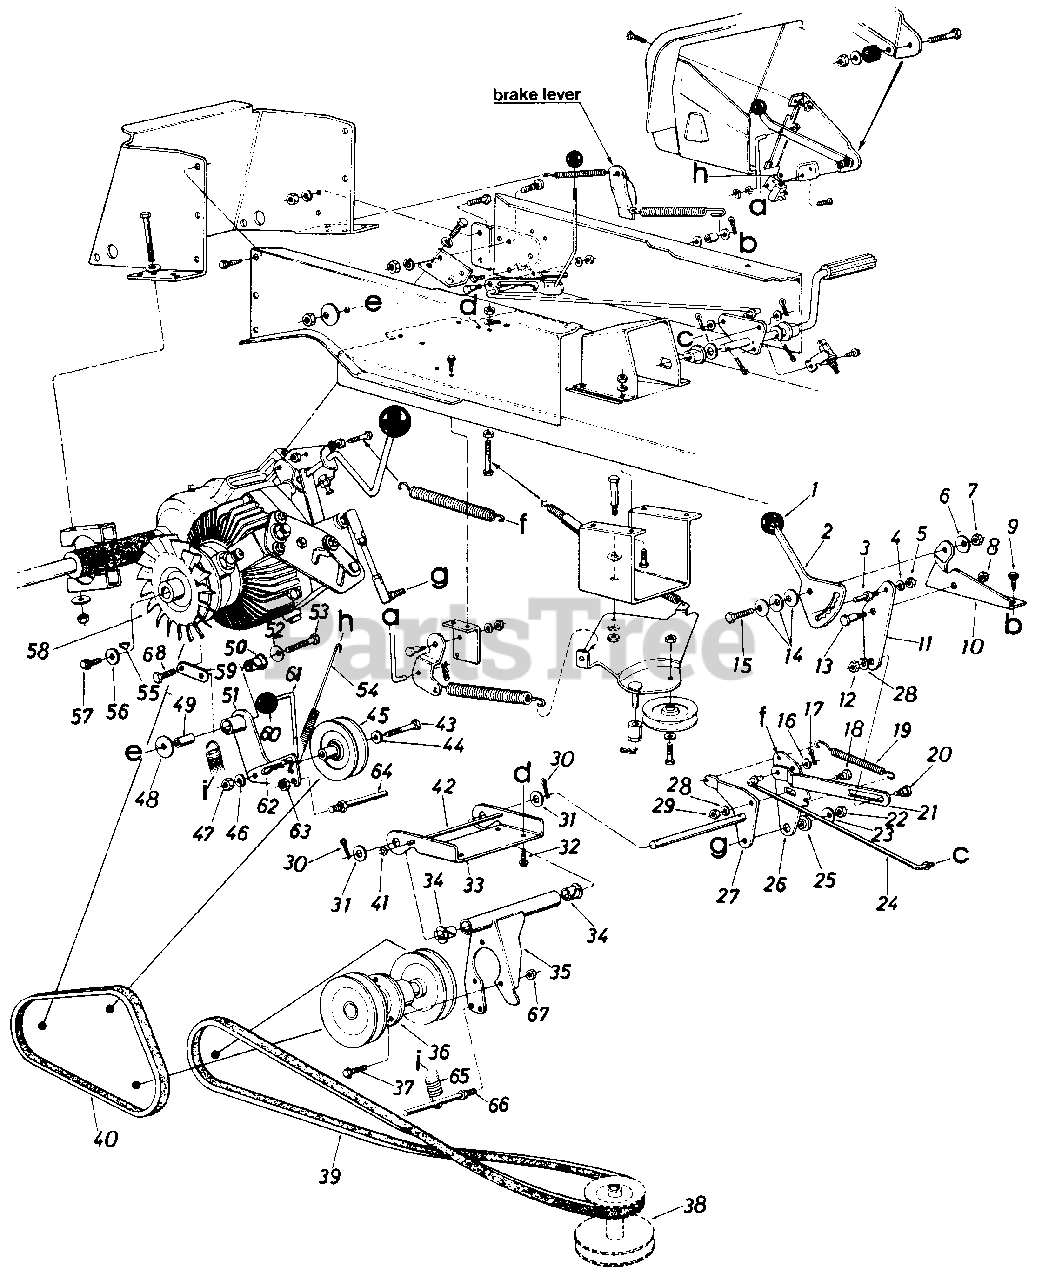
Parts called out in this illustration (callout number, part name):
1	Gear Shift Knob
2	Speed Selector Cam
3	Hex Stud .250" Dia. x .62"
4	L-Wash. 1/4" I.D.
5	Hex Nut 1/4-20 Thd.
6	Bell-Wash. .400" I.D. x 1.13" O.D.
7	Hex Ins. L-Nut 3/8-24 Thd.
8	Hex Top L-Nut 3/8-16 Thd.
9	Hex Wash. Hd. S-Tap Scr. 1/4-20 x .75" Lg.
10	Speed Selector Mtg. Brkt.
11	Speed Selector Transfer Brkt.
12	Hex Nut 5/16-18 Thd.
13	Shld. Bolt .500" Dia. x .170
14	Bell-Wash. .39" I.D. x 1.13" O.D.
15	Hex Bolt 3/8-24 x 1.00" Lg.
16	Fl-Wash. .385" I.D. x .87" O.D.
17	Cotter Pin 3/32" Dia. x .75" Lg.*
18	Shld. Bolt .437" Dia. x .180
19	Extension Spring .50" Dia. x 2.75" Lg.
20	Shld. Bolt .437" Dia. x .180
21	Speed Selector Link
22	Hex Nut 3/8-24 Thd.
23	Bell-Wash .39" I.D. x 1.13" O.D.
24	Rod-Speed Control .312" Dia.
25	Shld. Spacer .625" I.D.
26	Speed Cont. Transfer Swivel Brkt.
27	Speed Control Transfer Ass'y.
28	L-Wash. 5/16" l.D.
29	Hex Nut 5/16-18 Thd.
30	Cotter Pin 1/8" Dia. x 1.00" Lg.*
31	Fl-Wash. .640" I.D. x 1.24" O.D.
32	Hex Wash S-Tap Scr. 1/4-20 x .50" Lg.
33	Idler Mtg. Brkt.
34	Flanged Nyliner Brg. .376 I.D. x .437
35	Mounting Brkt. Ass'y.
36	Jack Shaft Ass'y.
37	Hex Sems Bolt 5/16-18 x .75" Lg.
38	Engine Pulley 47.5" I.D. x 5.56" O.D.
39	"V"-Belt
40	"V"-Belt
41	Push Cap
42	Rod-3/16" Dia. x 7.12" Lg.
43	Hex Bolt 3/8-24 x 1.50" Lg.
44	Fl-Wash. .385" I.D. x .87" O.D.
45	Idler Pulley 4.0" O.D. x 5l8"-"V"
46	L-Wash. 3/8" I.D.
47	Hex Nut 3/8-24 Thd.
48	Bell-Wash. .40" I.D. x .87" O.D.
49	Spacer .38" I.D. x .62" O.D. x 1.87" Lg.
50	Flanged Nyliner Brg.
51	Idler Pivot Brkt. Ass'y.
52	Fl-Wash. .38" I.D. x .87" O.D.
53	Hex Bolt 3/8-24 x 2.00" Lg.
54	Extension Spring .56" O.D. x 7.75" Lg.
55	#9 Hi-Pro Key .316" x .75" Dia.
56	Fl-Wash. .505" I.D. x 1.0" O.D.
57	Hex Wash. Hd. S-Tap Scr. 1/4-20 x .75" Lg.
58	Trans. Pulley Fan Ass'y.
59	Link
60	Ball Knob
61	Push Rod
62	Intern. Cotter Pin
63	Hex L-Nut 1/4-20 Thd.
64	Belt Guard Pin
65	Ext. Spring 6.12 Lg.
66	Stud 3/8-16 x 3.62
67	Hex Top L-Nut 3/8-16 Thd.
68	Part of Hydrostatic Pump
